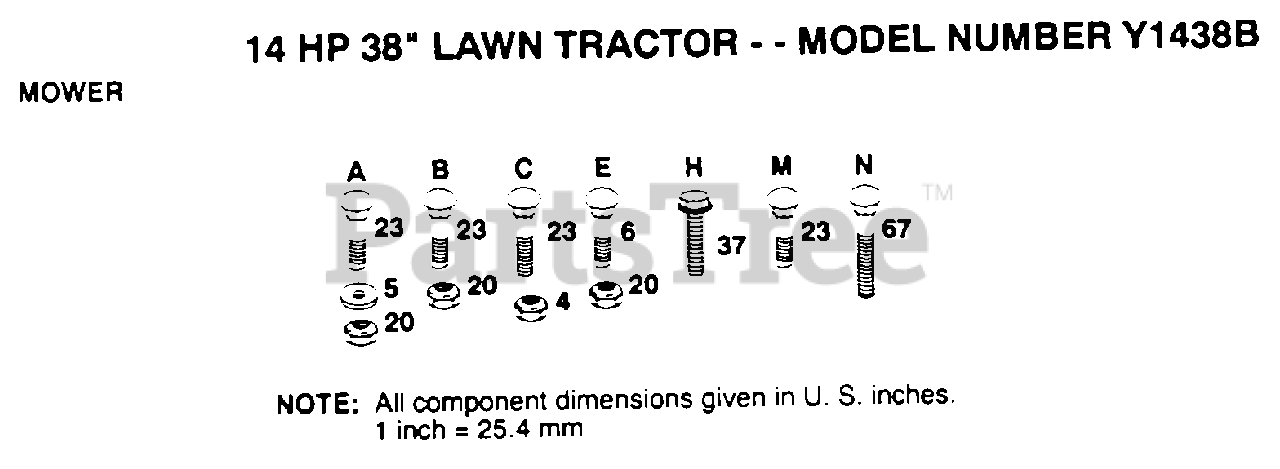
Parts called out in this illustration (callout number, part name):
5	WASHER M
6	BOLT
23	BOLT
37	SCREW
67	BOLT.3/8-14X1.25
